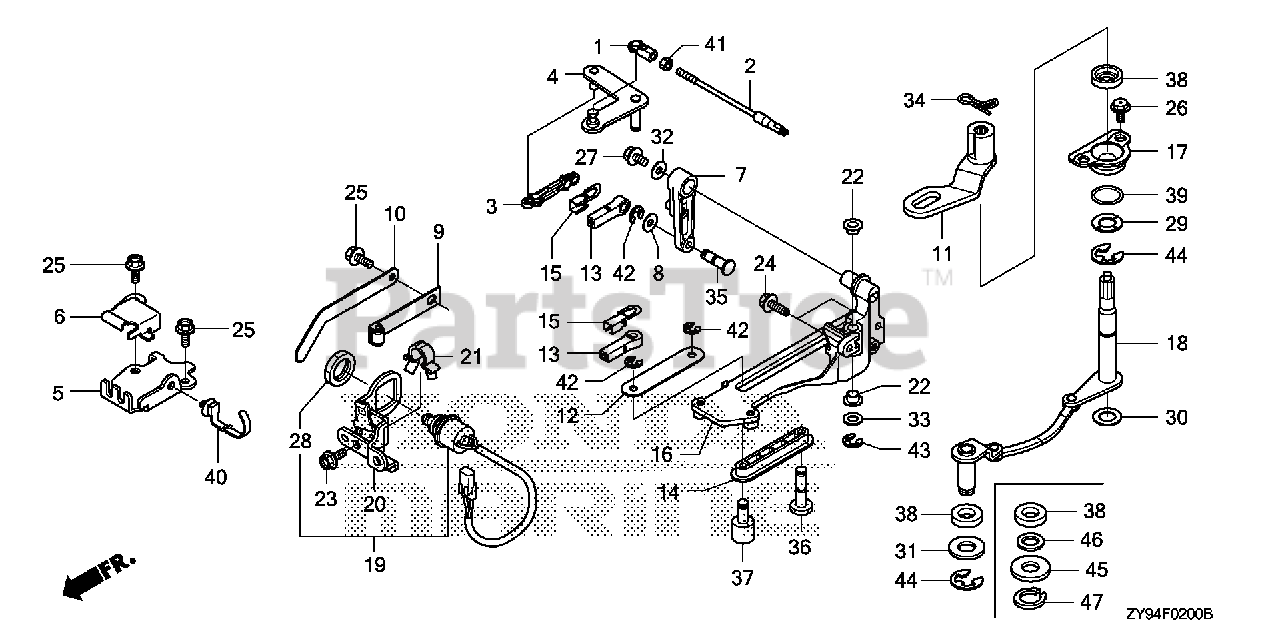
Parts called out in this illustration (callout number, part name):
1	LINKAGE, PIVOT
2	ROD, THROTTLE
3	LINK, THROTTLE
4	PLATE, THROTTLE
5	PLATE, REMOTE CONTROL CABLE
6	COVER, REMOTE CONTROL CABLE
7	ARM, THROTTLE
8	WASHER, PIVOT
9	SPRING, CLICK
10	SPRING, CLICK ASSIST
11	ARM, SHIFT
12	PLATE, SHIFT PIVOT
13	PIVOT, SHIFT
14	PIVOT, SHIFT SLIDE
15	PLATE, LOCK
16	BRACKET, SHIFT LINK
17	HOLDER, SEAL
18	SHAFT, SHIFT
19	SWITCH ASSY., NEUTRAL
20	BRACKET, NEUTRAL SWITCH (NOT AVAILABLE)
20	BRACKET, NEUTRAL SWITCH
21	CLIP, BRAKE PIPE (A)
22	BUSH A, COVER LOCK
23	BOLT, FLANGE (6X14) (CT200)
24	BOLT, FLANGE (6X18) (CT200)
25	BOLT, FLANGE (6X16)
26	BOLT, FLANGE (6X11)
27	BOLT, FLANGE (6X12)
28	NUT, HEX. (20MM)
29	WASHER, SIDE (14MM)
30	WASHER, SHIFT SHAFT
31	WASHER
32	WASHER, PLAIN (6MM)
33	WASHER, PLAIN (8MM)
34	PIN, SNAP (6MM)
36	PIN, SHIFT LINK
38	SEAL, WATER (14X26X6)
39	O-RING (27X2) (ARAI)
40	CLIP, HARNESS BAND (155.3MM) (BLACK)
41	NUT, HEX. (5MM)
42	E-RING (4MM)
43	E-RING (6MM)
44	E-RING (12MM)
45	WASHER (14MM)
46	WASHER (13MM)
47	CIRCLIP (OUTER) (12)
